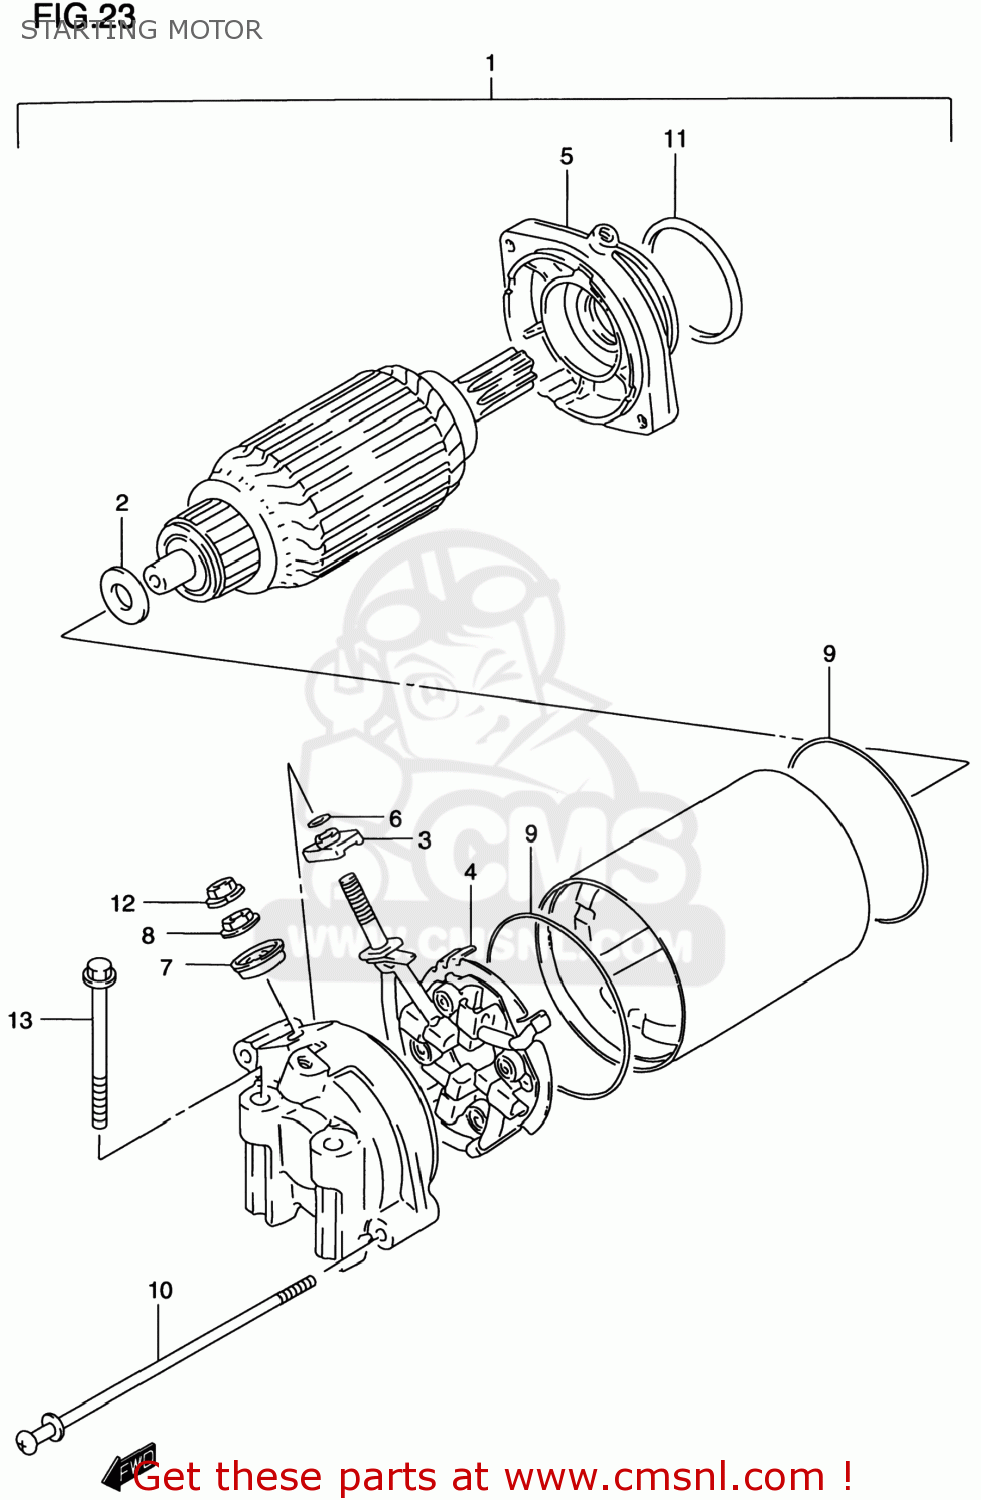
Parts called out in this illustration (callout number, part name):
1	MOTOR ASSY,STARTING
2	SHIM SET,STARTING MOTOR
3	O RING
4	HOLDER SET,BRUSH
5	BRACKET SET
6	BUSHING
7	BUSHING
8	NUT
9	O RING
10	BOLT
11	O RING
12	NUT
13	BOLT
